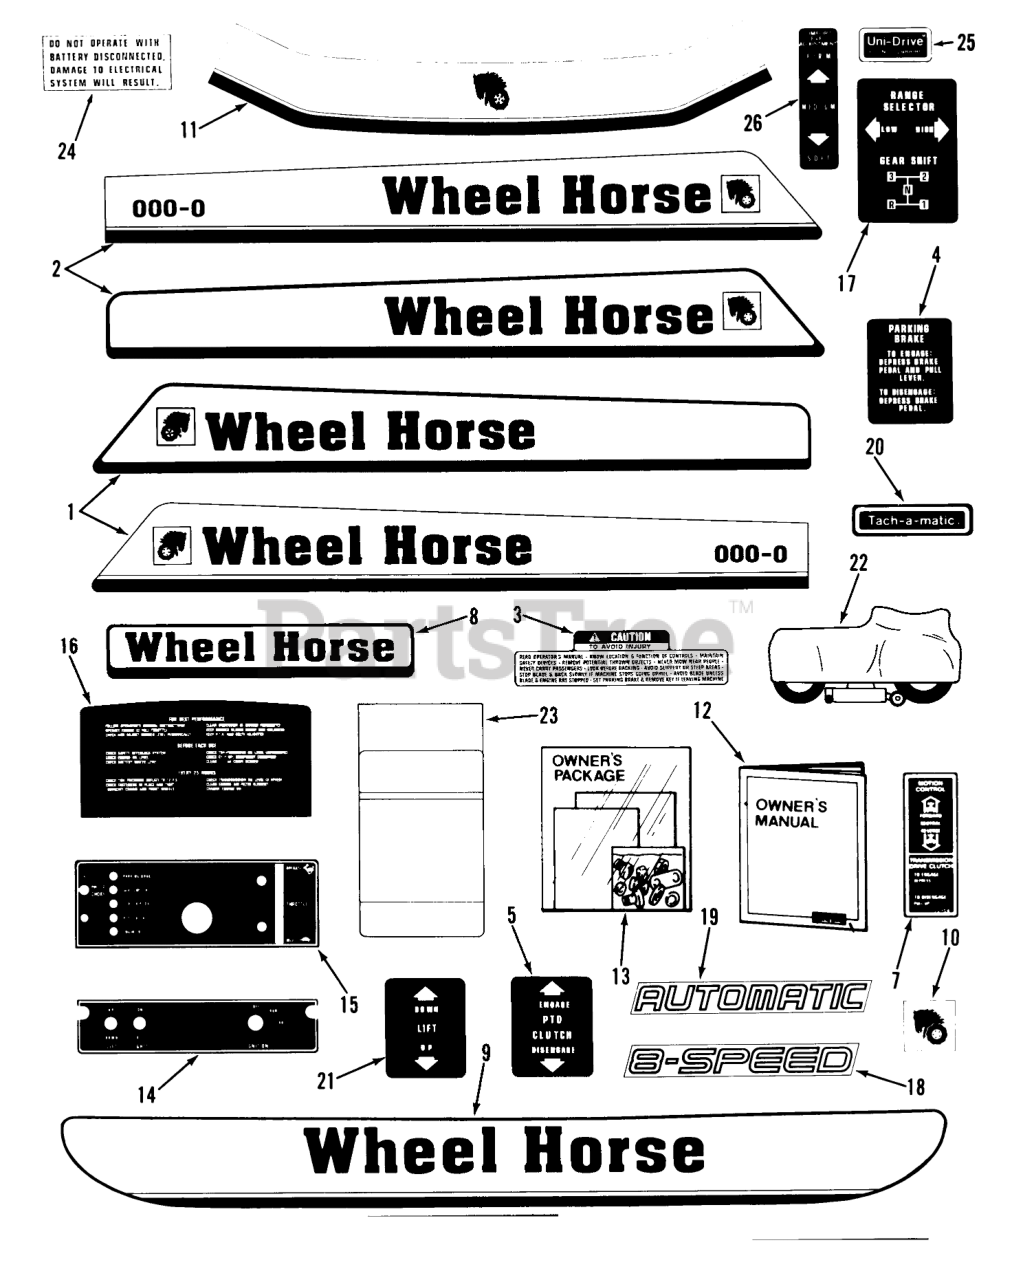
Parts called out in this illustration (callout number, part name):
1	DECAL-HOOD RH
2	DECAL-HOOD LH
3	DECAL CAUTION
4	DECAL-PARKING, BRAKE
5	DECAL PTO
7	DECAL SPD CONTROL
8	DECAL REAR FENDER
9	Decal-Rear Fender
10	DECAL HOOD FRONT
11	Decal-Hood Front
12	Owners Manual-Tractor
13	Loose Parts Package 312-A, 312-8, 414-8
13	Loose Parts Package 308-8
14	DECAL BACK PLATE
15	Decal-Lower Dash 416
15	DECAL LOWER DASH
16	Decal-Rear Hood
16	DECAL REAR HOOD
17	DECAL-SHIFT PATTERN
18	DECAL 8SPD
19	DECAL AUTOMATIC
20	DECAL-TACHAMATIC
21	DECAL LIFT
22	Vinyl Tractor Cover
23	Decal-Maintenance
24	DECAL ELECT SYSTEM
25	DECAL UNI-DRIVE
26	DECAL SEAT
